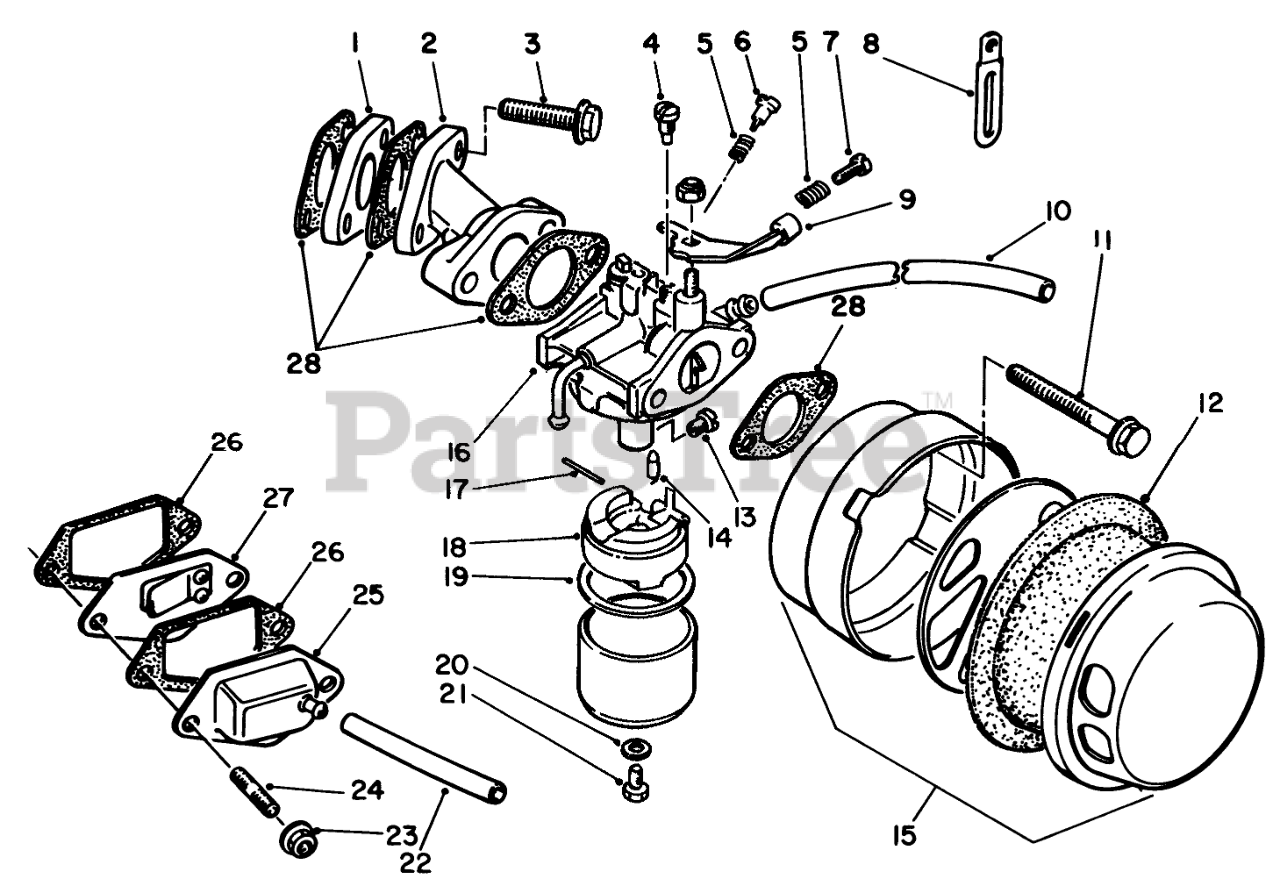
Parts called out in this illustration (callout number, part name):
1	Insulator
4	Jet
5	SPRING
6	ADJUSTER
7	SCREW
8	CLAMP
9	Lever-Choke
10	Hose-Overflow
11	Screw-Hex Flange Hd.
12	FILTER FOAM
13	Jet-Main
14	NEEDLE ASSM.
15	Air Cleaner Assembly
16	Carburetor Assembly (Incl. Items #13,14,17-21)
17	Pin
18	FLOAT
19	GASKET
20	GASKET
21	Screw-Hex Hd.
24	Bolt-Stud
25	Cap-Breather
26	Gasket
27	REED VALVE
28	GASKET
